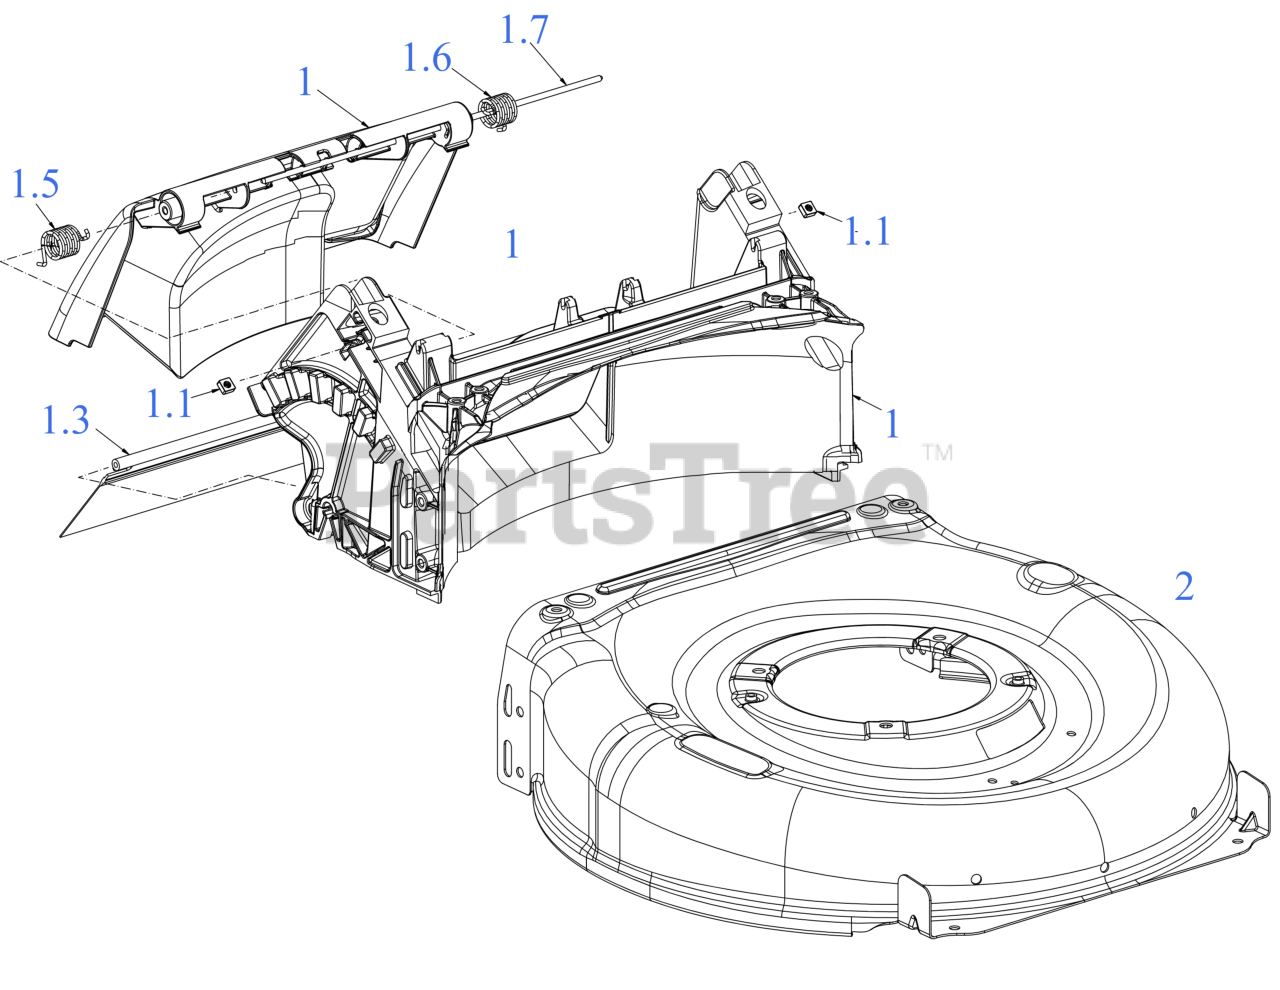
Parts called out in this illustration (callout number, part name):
1	REAR DOOR & BAFFLE ASSEMBLY
1.1	SQUARE NUT 1/4-20
1.3	TRAILSHIELD
1.5	TORSION SPRING (RH)
1.6	TORSION SPRING (LH)
1.7	REAR DOOR PIVOT ROD
